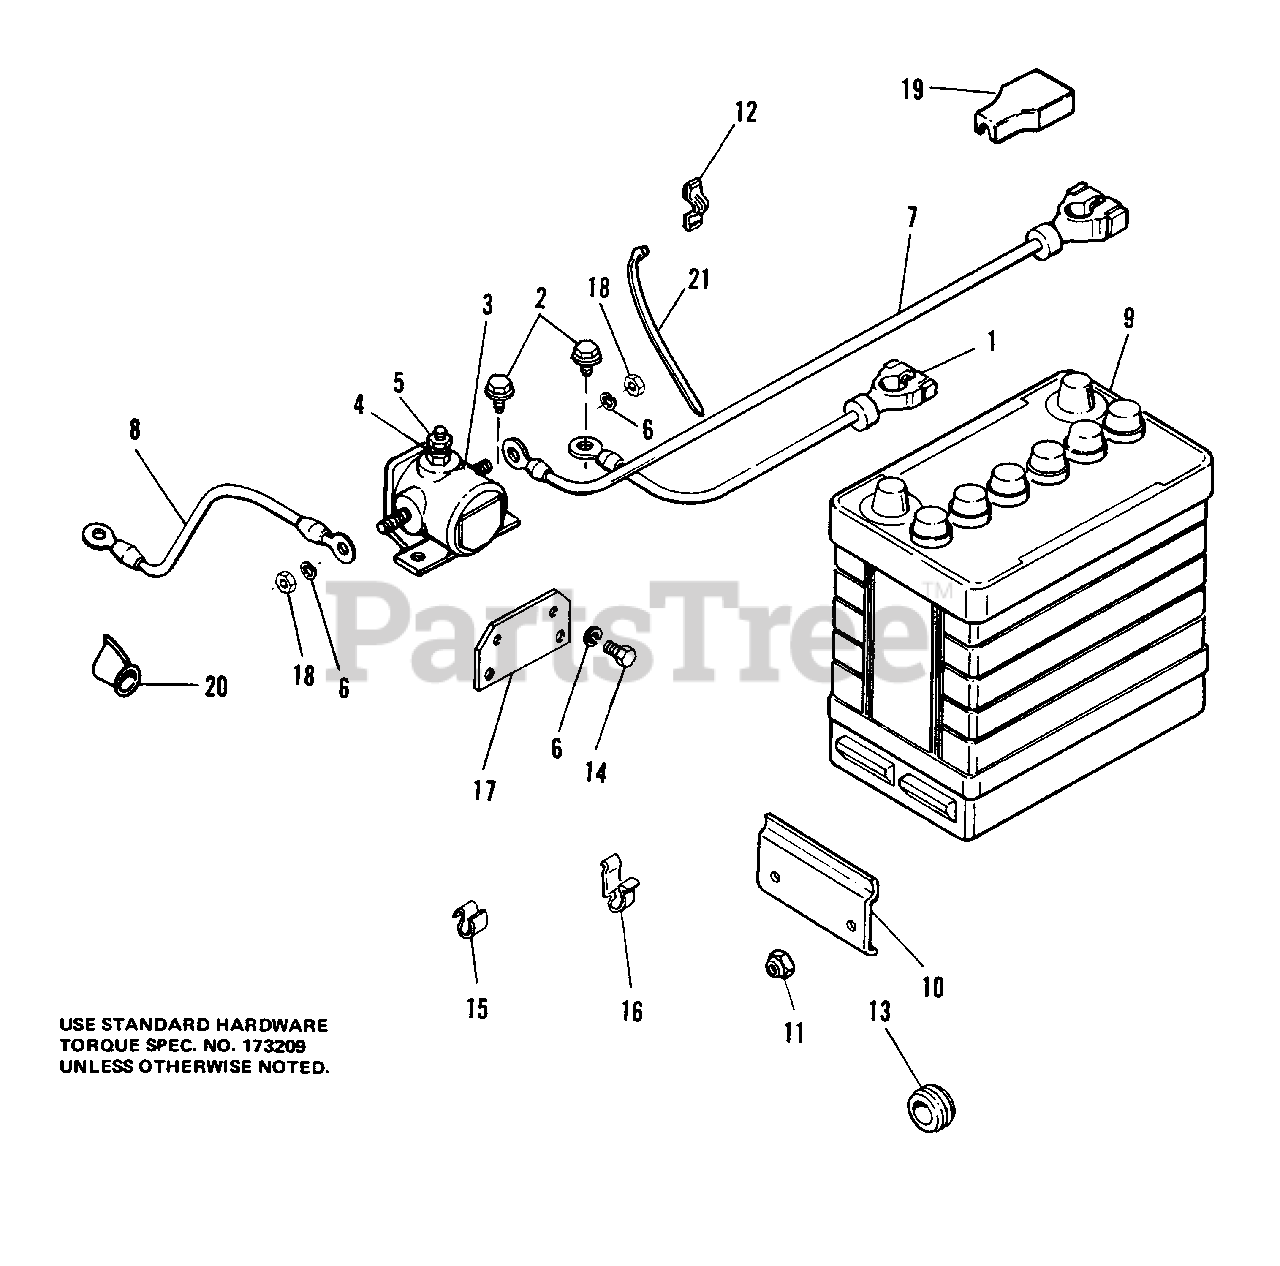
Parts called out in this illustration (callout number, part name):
1	CABLE, Battery to Ground
2	SCREW, Taptite, 1/4-20 x 1/2
4	LOCKWASHER, No. 10
5	NUT, Hex, No. 10-32
6	LOCKWASHER, 5t16
7	CABLE, Battery to Solenoid
8	CABLE, Solenoid to Starter
11	NUT, Elastic, 5/16-18
12	CLIP, Wire
14	CAPSCREW, Hex Hd., 5/16-18 x 3/4
15	CLIP, Tinnermann
16	CLIP, Tinnermann
18	NUT, Hex
19	PROTECTOR, Terminal
20	COVER, Terminal
